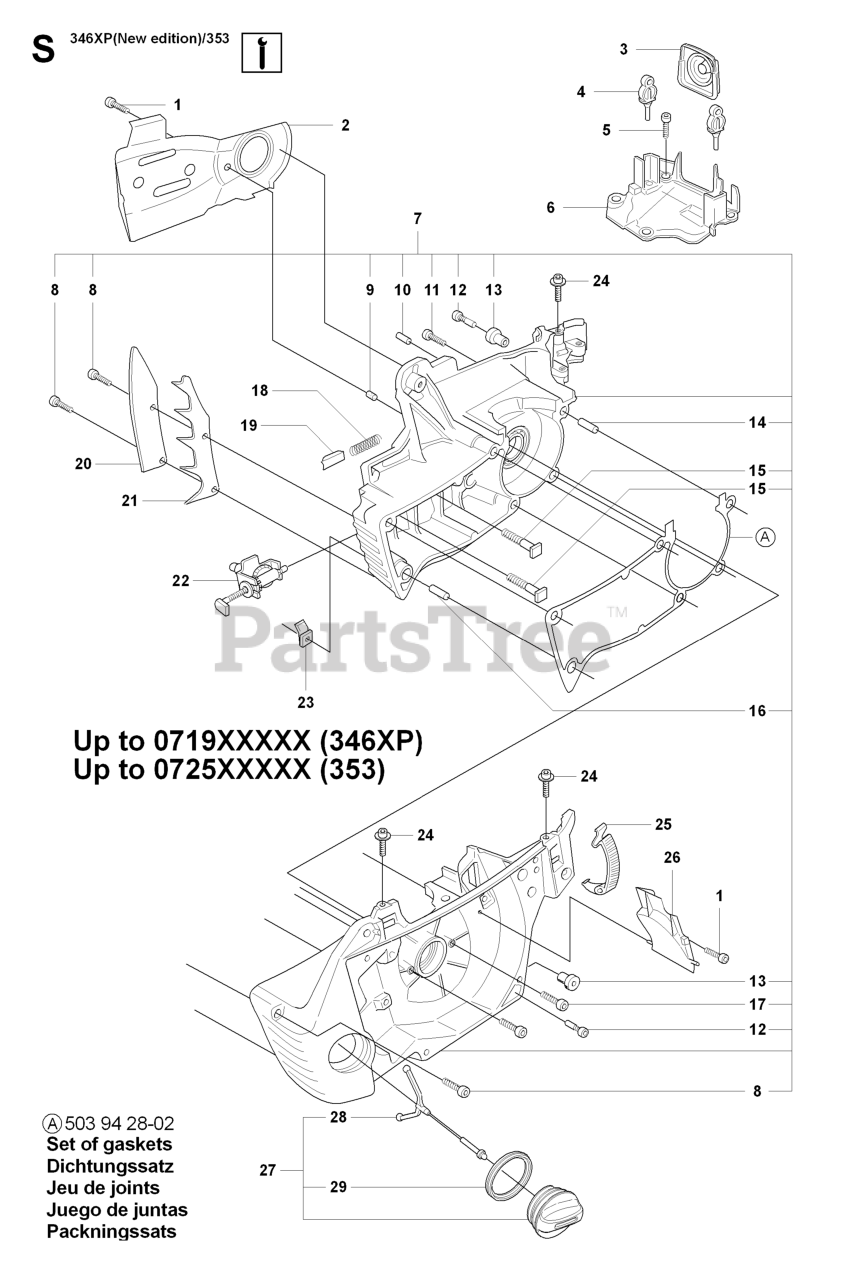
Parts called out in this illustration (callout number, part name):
7	CRANKCASE ASSY.
13	MOVEMENT LIMITER
18	LOCK SPRING
22	CHAIN TENSIONER
23	CHAIN CATCHER
25	BUCKLE ORANGE
27	OIL TANK CAP GREY
29	OILCAP GASKET
A	GASKET SET
